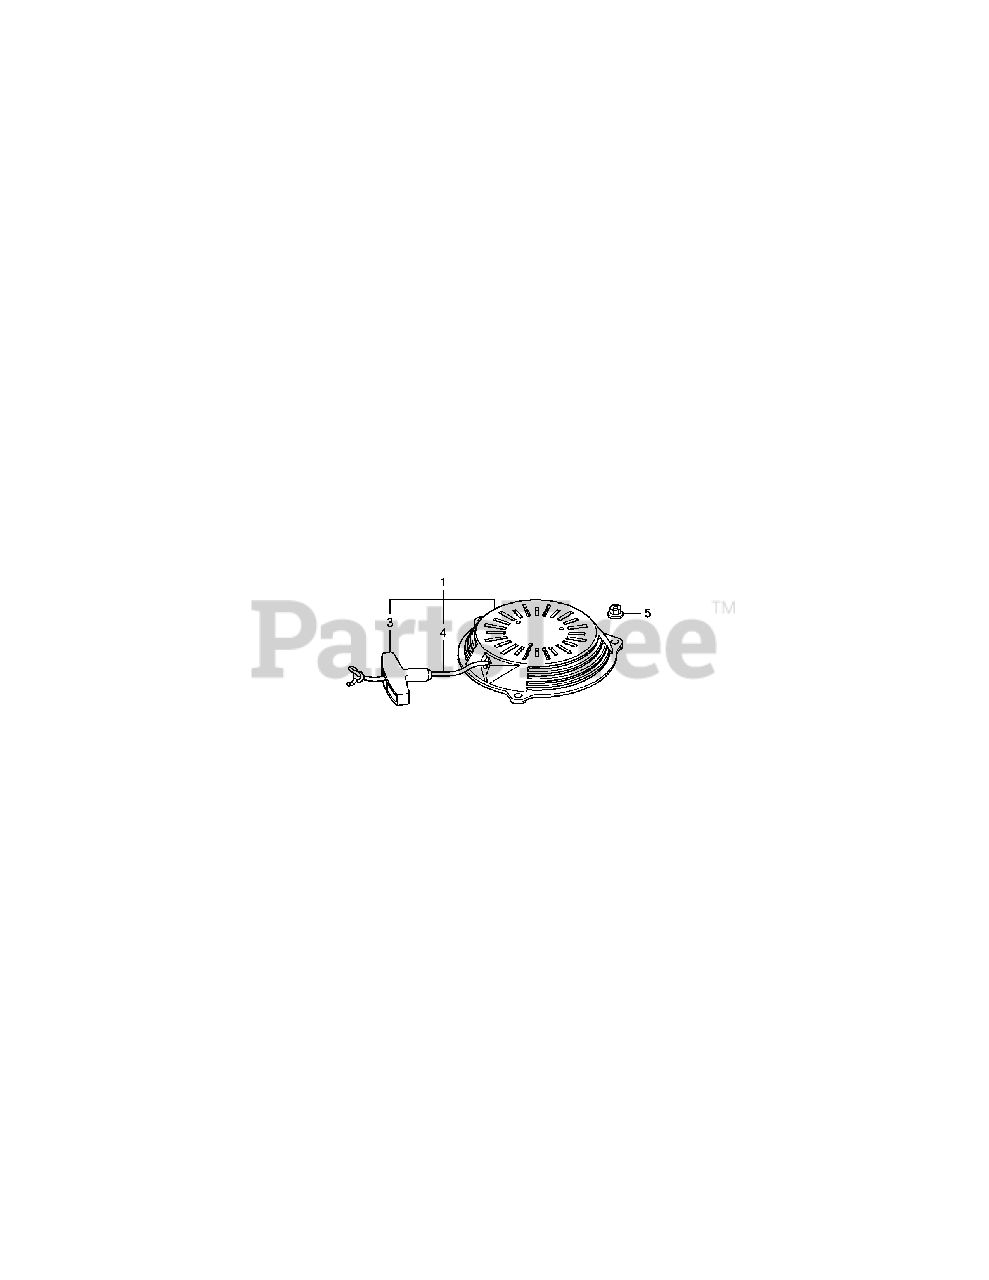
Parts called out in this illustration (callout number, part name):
1	Recoil Starter Assembly
3	Starter Grip
4	Recoil Starter Rope
5	Flange Nut, 6mm
